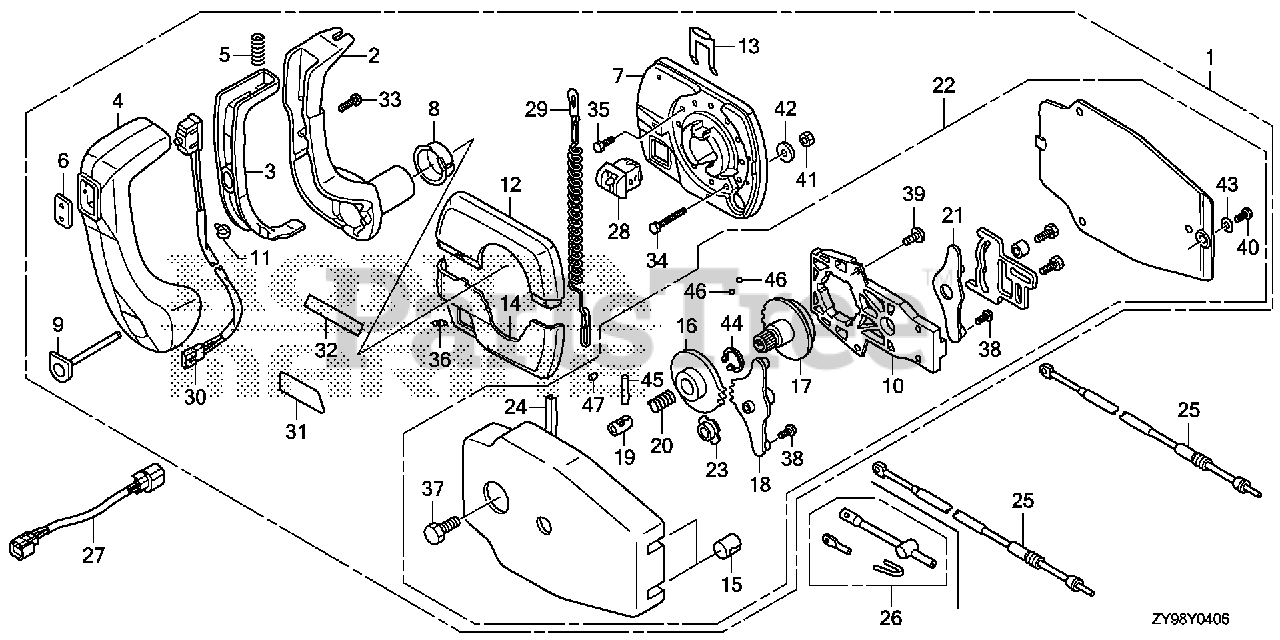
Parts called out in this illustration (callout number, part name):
1	BOX ASSY., REMOTE CONTROL (PANEL MOUNT) (NA USE ALT:06240-ZW7-U00)
2	HANDLE, REMOTE CONTROL
3	LEVER, HANDLE LOCK
4	GRIP, REMOTE CONTROL HANDLE
5	SPRING, REMOTE CONTROL HANDLE
6	COVER, GRIP
7	HOUSING ASSY., REMOTE CONTROL BOX (A)
8	BUSHING
9	BUTTON, THROTTLE
10	FRAME ASSY., REMOTE CONTROL BOX
11	BAND B, CABLE
12	HOUSING, REMOTE CONTROL BOX (B)
13	RETAINER
14	HOUSING, REMOTE CONTROL BOX (C)
15	GROMMET
16	WHEEL, CONTROL
17	SHAFT, HANDLE (NOT AVAILABLE)
18	ARM ASSY., SHIFT LINK
19	SHAFT, GEARSHIFT
20	SPRING, GEARSHIFT
21	ARM ASSY., THROTTLE LINK
22	HOUSING ASSY. (INNER) (PANEL MOUNT)
23	BUSH
24	SPRING
25	CABLE, REMOTE CONTROL (10') (TELEFLEX)
25	CABLE, REMOTE CONTROL (10') (BRUNSWICK)
25	CABLE, REMOTE CONTROL (11') (TELEFLEX)
25	CABLE, REMOTE CONTROL (11') (BRUNSWICK) (NOT AVAILABLE)
25	CABLE, REMOTE CONTROL (12') (TELEFLEX)
25	CABLE, REMOTE CONTROL (12') (BRUNSWICK) (NOT AVAILABLE)
25	CABLE, REMOTE CONTROL (13') (TELEFLEX)
25	CABLE, REMOTE CONTROL (13') (BRUNSWICK) (NOT AVAILABLE)
25	CABLE, REMOTE CONTROL (14') (TELEFLEX)
25	CABLE, REMOTE CONTROL (14') (BRUNSWICK) (NOT AVAILABLE)
25	CABLE, REMOTE CONTROL (15') (TELEFLEX)
25	CABLE, REMOTE CONTROL (15') (BRUNSWICK) (NOT AVAILABLE)
25	CABLE, REMOTE CONTROL (16') (TELEFLEX)
25	CABLE, REMOTE CONTROL (16') (BRUNSWICK) (NOT AVAILABLE)
25	CABLE, REMOTE CONTROL (17') (TELEFLEX)
25	CABLE, REMOTE CONTROL (17') (BRUNSWICK) (NOT AVAILABLE)
25	CABLE, REMOTE CONTROL (18') (TELEFLEX)
25	CABLE, REMOTE CONTROL (18') (BRUNSWICK) (NOT AVAILABLE)
25	CABLE, REMOTE CONTROL (19') (TELEFLEX)
25	CABLE, REMOTE CONTROL (19') (BRUNSWICK) (NOT AVAILABLE)
25	CABLE, REMOTE CONTROL (20') (TELEFLEX)
25	CABLE, REMOTE CONTROL (20') (BRUNSWICK) (NOT AVAILABLE) (ALT. PNO: 24920-ZW1-003AH)
26	ADAPTER, REMOCON CABLE (N/A: USE 24931-ZW1-000)
27	HARNESS ASSY., POWER TRIM-TILT
28	SWITCH ASSY., EMERGENCY STOP
29	WIRE, EMERGENCY
30	SWITCH ASSY., POWER TRIM-TILT (A)
31	MARK, REMOTE CONTROL (A)(PANEL)
32	MARK, REMOTE CONTROL (B)(FOR STARBOARD)
32	MARK, REMOTE CONTROL (C)(FOR PORT)
33	SCREW A (NOT AVAILABLE)
34	SCREW B
35	SCREW C
36	SCREW SET (1/4-20X16")
37	BOLT
38	SCREW (8-32X3/8)
39	SCREW (10-32X5/8)
40	SCREW (10-32X5/8)
41	NUT (1/4X20)
42	WASHER
43	WASHER
44	CIRCLIP (OUTER)
45	PIN, GEARSHIFT
46	BALL, STEEL
47	ROLLER, SHIFT CLICK
